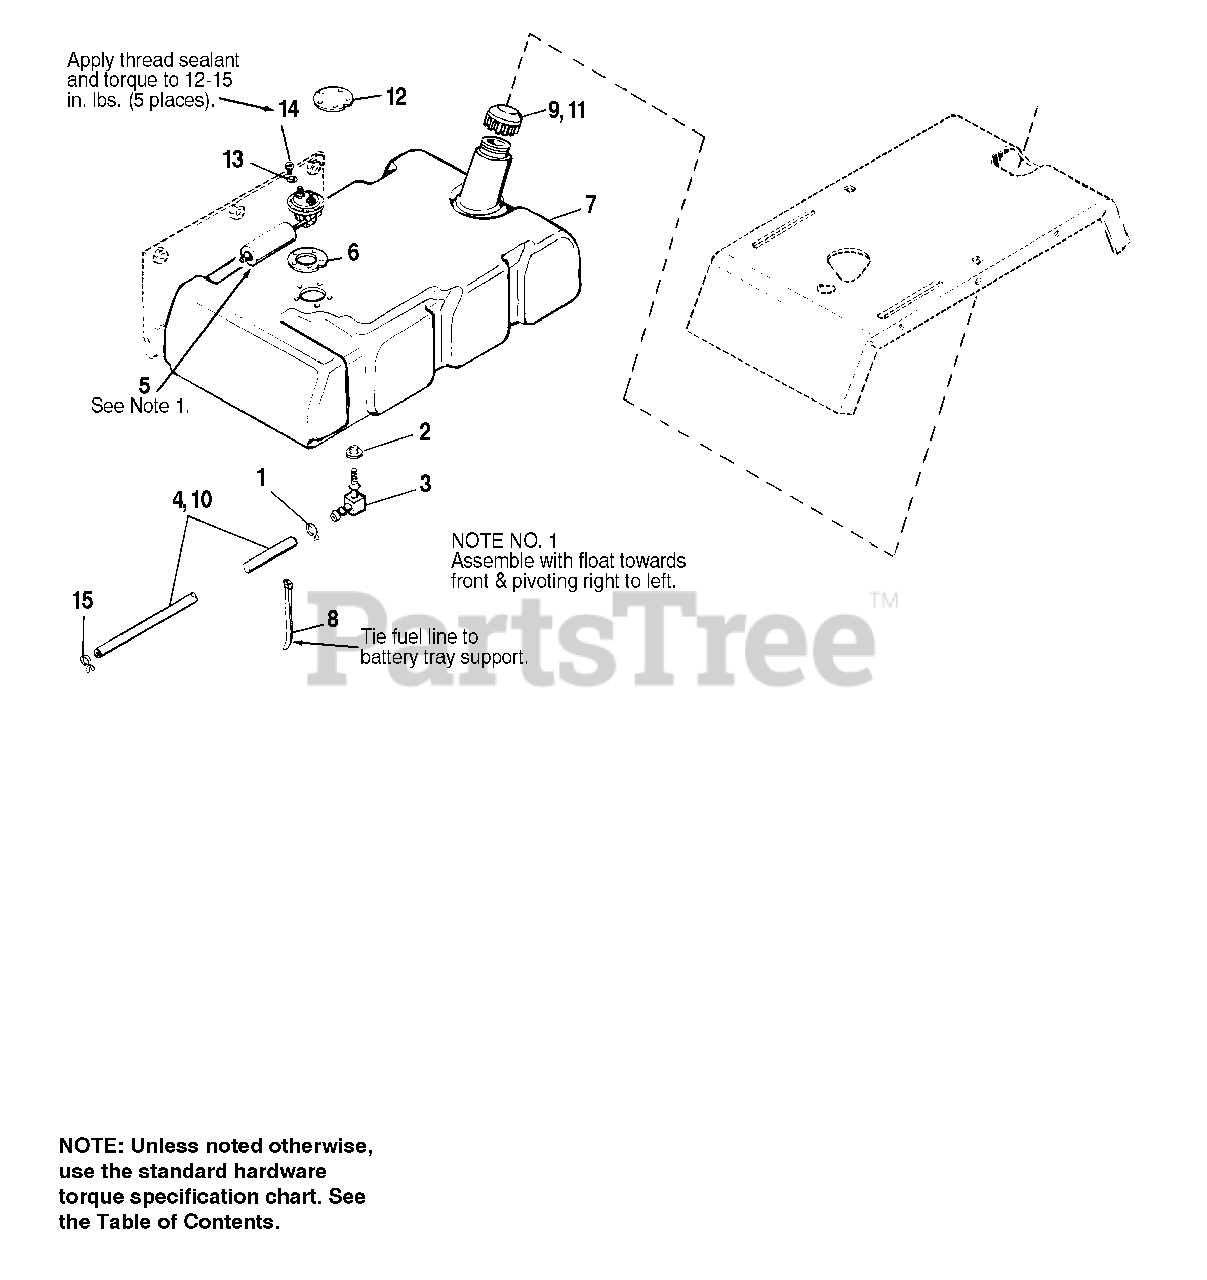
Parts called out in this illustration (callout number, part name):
1	CLAMP, Hose
3	ELBOW, with Screen
4	HOSE, Fuel, 45.5 Long
5	SENDER, Fuel Level
7	FUEL TANK, w/Fittings & Gasket
8	TIE, Self-Locking
9	CAP, Fuel, w/Gauge
10	HOSE, Fuel, 38" Long
11	CAP, Fuel, Vented
12	PLATE
14	SCREW, Truss Hd., #10-32 x 1/2
15	CLAMP, Hose
